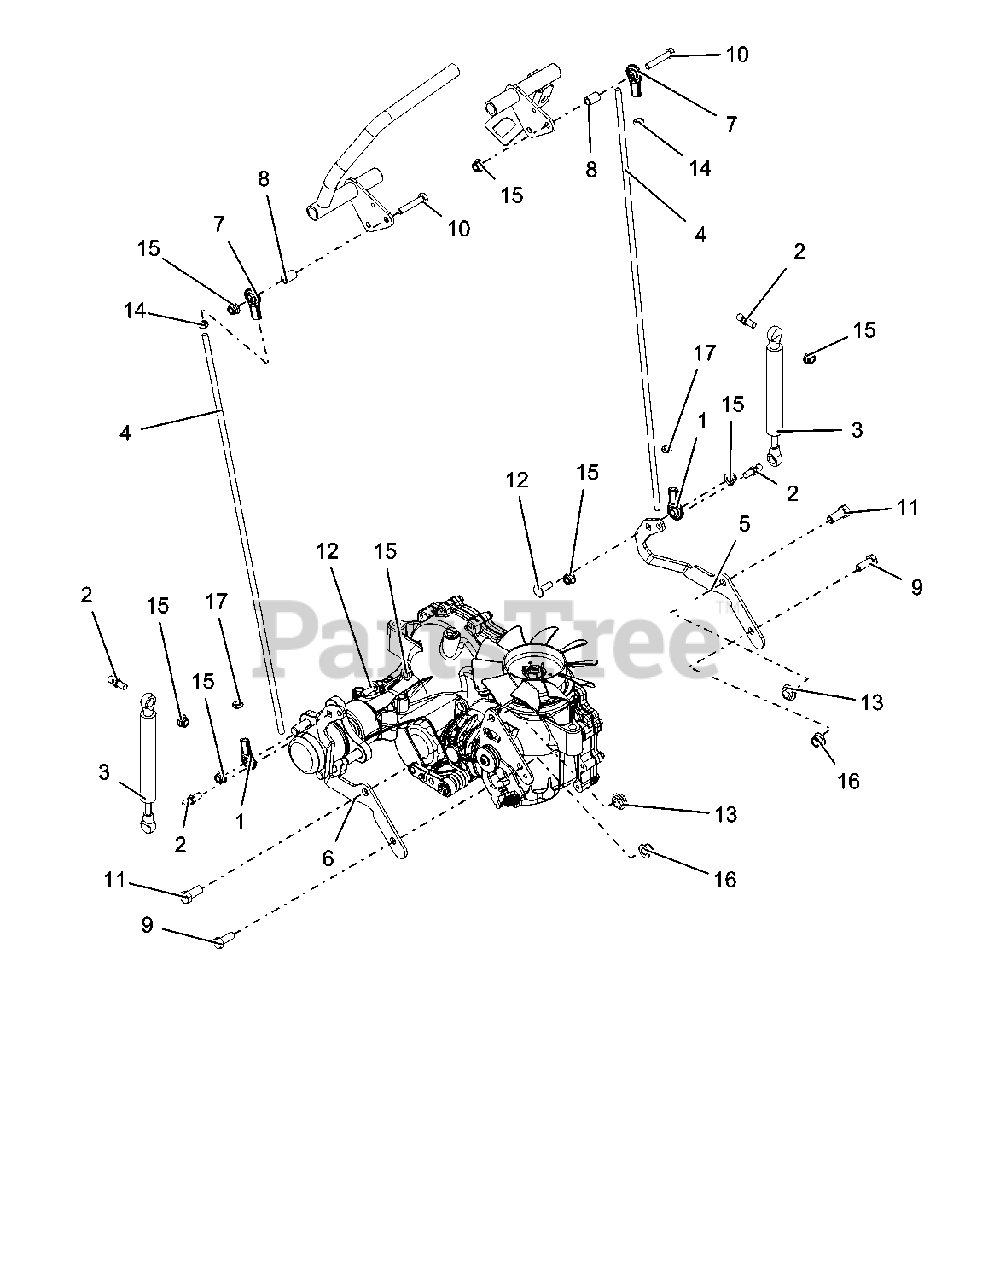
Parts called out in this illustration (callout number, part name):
1	ALIGNABALL, 5/16 RH THREAD
2	STUD- BALL
3	DAMPER, CONTROL
4	ROD, STEERING
5	BRKT, LH TRANS CONTROL
6	BRKT, RH TRANS CONTROL
7	ALIGNABALL, 5/16 LH THREAD
8	BSHG-SLV .328X.50X.75
9	@BLT-HEX .38-16X1.00 GR5 YWZC
10	@BLT-HEX .31-18X1.75 GR5 YWZC
11	@BLT-HEX .44-14X1.00 GR5 YWZC
12	@BLT-RDHDSQNK .31-18X1.00 G5YZ
13	@NUT-LK-NYL-FLG .44-14 YWZC
14	NUT-JAM LH .31-24 YWZC
15	@NUT-LK-NYL-FLG .31-18 YWZC
16	@NUT-LK-NYL-FLG .38-16 YWZC
17	NUT-JAM .31-24 YWZC
